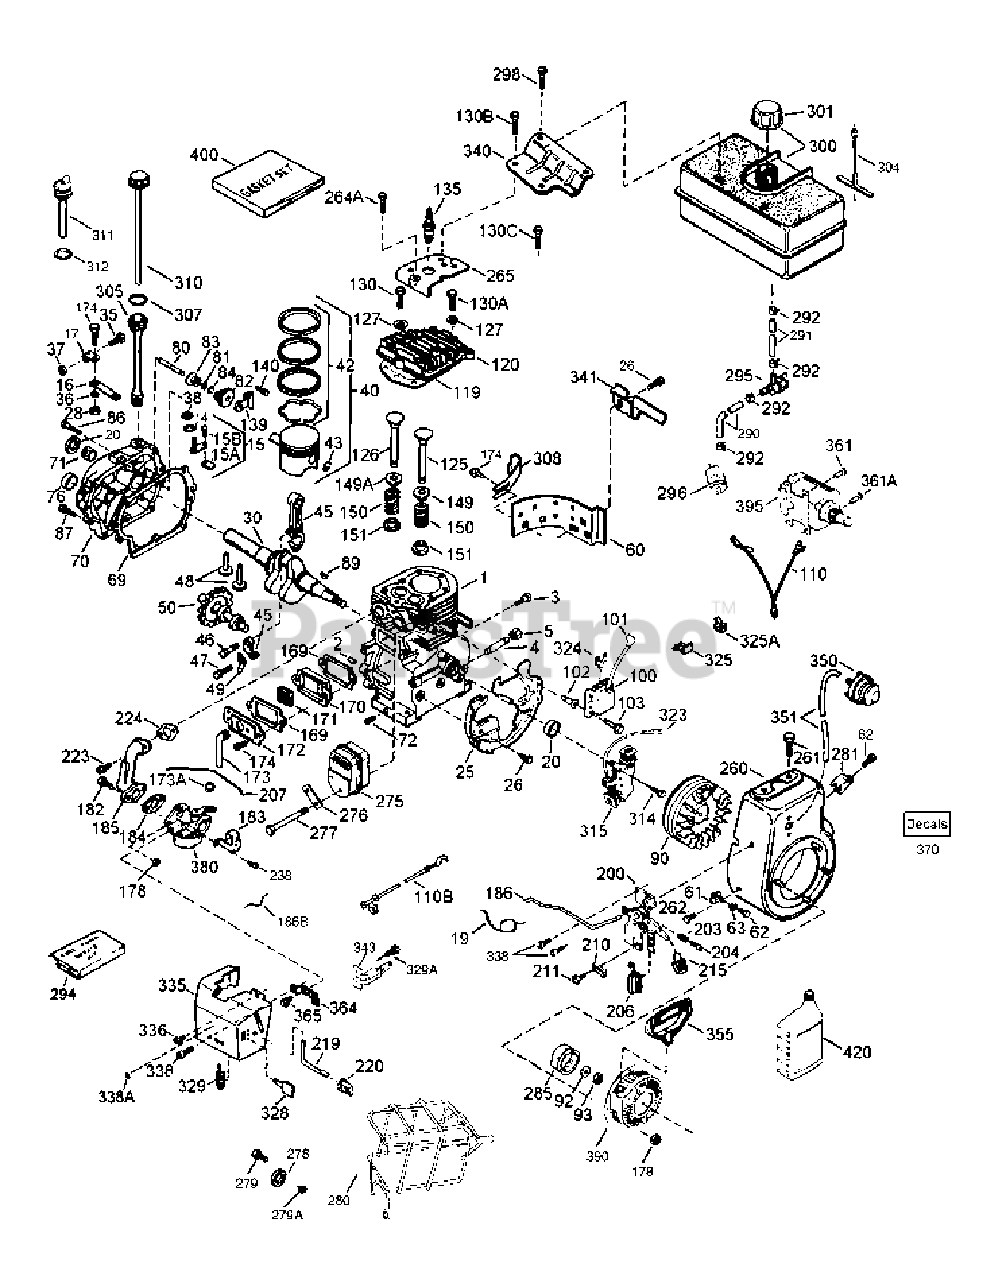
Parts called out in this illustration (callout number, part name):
1	Cylinder Ass'y. Incl. 2, 20, 72 & 72A 3-1/8" Bore
2	Dowel Pin
3	Screw, 1/4-20 x 1/2"
4	Oil Drain Extension
5	Extension Cap, 1/4-18 NPT
14	Flat Washer
15	Governor Rod Incl. 15A & 15B
15A	Governor Yoke
15B	Screw, 6-40 x 5/16"
16	Governor Lever
17	Governor Lever Clamp
18	Screw, T-15, 8-32 x 7/16"
19	Speed Control Spring
25	Blower Housing Baffle
26	Screw 1/4-20 x 19/32"
28	Lock Nut, 8-32
30	Crankshaft
35	Screw, 10-32 x 3/4"
36	Lock Washer #8
37	Lock Nut, 10-32
38	Retaining Ring
40	Piston, Pin & Ring Set .010" OS Incl. 41, 42 & 43
40	Piston, Pin & Ring Set Std. Incl. 41, 42 & 43
42	Ring Set .010" OS
42	Ring Set Std.
43	Piston Pin Retaining Ring
45	Connecting Rod Assembly Incl. 47 & 49
47	Connecting Rod Bolt 1/4-20 x 1-5/16"
48	Valve Lifter
49	Oil Dipper
50	Camshaft MCR
60	Blower Housing Extension
69	Cylinder Cover Gasket
70	Cylilnder Cover Incl. 71, 75, 80 thru 84
71	Crankshaft Bushing
80	Governor Shaft
82	Governor Gear Ass'y. Incl. 81
83	Governor Spool
84	Retaining Ring
86	Screw 1/4-20 x 1-3/16"
87	Screw, 1/4-20 x 1- 11/16"
89	Flywheel Key
90	Flywheel 3 Amp, w/ring gear
92	Belleville Washer
93	Flywheel Nut 5/8-18
100	Solid State Ignition Incl. 101
101	Spark Plug Cover
102	Solid State Mounting Stud
103	Screw, T-15, 10-24 x 15/16"
110	Ground Wire
119	Cylinder Head Gasket
120	Cylinder Head
125	Exhaust Valve 1/32" OS Incl. 151
125	Exhaust Valve Std.Incl. 151
126	Intake Valve Std. Incl. 151
127	Flat Washer
130	Screw, 5/16-18 x 1-7/16"
130C	Screw, 5/16-18 x 39/64"
135	Resistor Spark Plug RJ19LM
139	Governor Gear Bracket
140	Screw, 10-24 x 1/2"
149	Valve Spring Cap
149A	Intake Valve Seal
150	Valve Spring
151	Valve Spring Cap
169	Valve Cover Gasket
170	Breather Body
171	Breather Element
172	Valve Cover
173	Breather Tube
174	Screw, 10-24 x 1/2"
178	Nut & Lock Washer 1/4-28
182	Screw, 1/4-28 x 1"
183	Choke Bracket
184	Carburetor-to-Intake Pipe Gasket
185	Intake Pipe
186	Governor Link
186B	Choke Spring
200	Manual Control Bracket Incl. 203, 204 & 206
203	Compression Spring
204	Screw, T-10, 5-40 x 7/16"
207	Throttle Link
211	Screw, 10-32 x 3/8"
215	Control Knob
219	Choke Rod
220	Control Knob
223	Screw, T-30, 5/16-18 x 1-3/32"
224	Intake Pipe Gasket
238	Screw, 10-32 x 1/2"
260	Blower Housing
261	Screw, 5/16-18 x 3/4"
262	Screw, 5/16-18 x 9/16"
264A	Screw, 1/4-20 x 5/8"
265	Cylinder Head Cover
276	Locking Plate
277	Screw, 5/16-18 x 4- 13/64"
285	Starter Cup
290	Fuel Line 32.0" length
292	Fuel Line Clamp
298	Screw, 1/4-15 x 3/4"
300	Fuel Tank Incl. 292 & 301 Black Poly 1 Gal,. 3.75 ltr.
301	Fuel Cap Red Plastic1-1/2" I.D.
305	Oil Fill Tube
308	Fill Tube Clip
314	Screw, 1/4-20 x 3/4"
315	Alternator Coil 18 Watt
325	Wire Clip
328	Ignition Key
329A	Screw, 8-32 x 23/64"
335	Carburetor Cover Incl. 328
336	Screw, 10-32 x 1/2"
338	Screw, 10-32 x 1/2"
340	Fuel Tank Bracket
341	Fuel Tank Bracket Lower
343	Key Switch Bracket Incl. 343A
350	Primer Assembly
351	Primer Line
355	Starter Handle Mitten Grip
361	Screw, T-30, 1/4-20 x 15/32"
361A	Screw, 6-32 x 2-1/2"
364	Carburetor Cover Bracket
365	Screw, 8-32 x 27/64"
370	Decal - Primer - International Symbol
370	Decal - Speed Control & Choke
370	Warning Decal
370	Decal - Tecumseh Logo for Top of Recoil Starter
370	Warning Decal Bilingual
380	Carburetor Incl. 184
390	Rewind Starter
400	Gasket Set
420	SAE 5W30 4-Cycle Engine Oil Quart Winter
702	Screw, 5/16-18 x 1-25/32"
999	Winter Maintenance Kit
